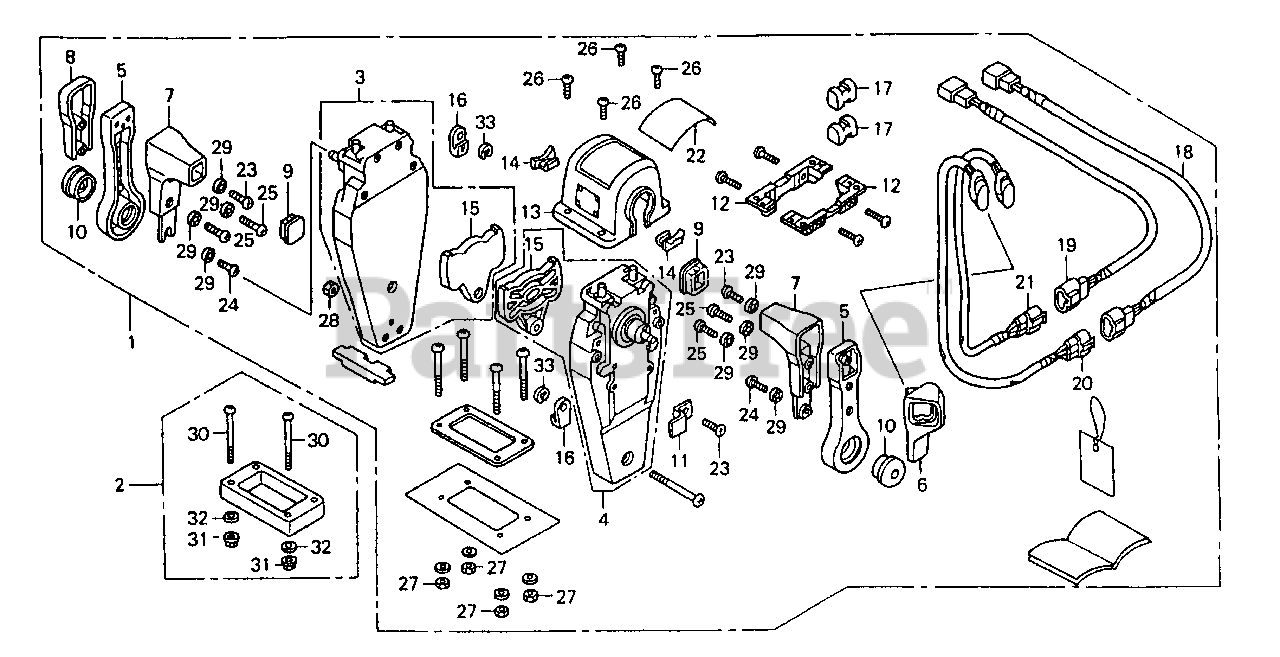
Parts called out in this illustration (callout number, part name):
1	BOX KIT, L. REMOTE CONTROL (TOP MOUNT DUAL)
2	SPACER, TOP DUAL
3	HOUSING ASSY., L. (INNER) (TOP MOUNT)
4	HOUSING ASSY., R. (INNER) (TOP MOUNT)
5	HANDLE, REMOTE CONTROL
6	COVER, L. GRIP
7	GRIP, REMOTE CONTROL HANDLE
8	COVER, DUAL GRIP
9	CAP, GRIP
10	BUTTON, THROTTLE
11	PLATE, CABLE CLAMP
12	BRACKET, REMOTE CONTROL HOUSING
13	HOUSING, DUAL REMOTE CONTROL BOX
14	HOUSING, LEAD
15	PLATE, DWELL
16	CABLE, TERMINAL
17	SPACER, CABLE CLAMP
18	SUB-HARNESS A ASSY., POWER TRIM-TILT
19	SUB-HARNESS B ASSY., POWER TRIM-TILT
20	SWITCH ASSY., POWER TRIM-TILT
21	SWITCH ASSY., POWER TRIM-TILT
22	MARK, REMOTE CONTROL (DUAL)
23	SCREW, PAN (5X16)
24	SCREW, PAN (5X10)
25	SCREW, PAN (5X20)
26	SCREW, PAN (4X10)
27	NUT, HEX. (5MM)
28	NUT, HEX. (5MM)
29	WASHER, LOCK (5MM)
30	SCREW, PAN (5X65)
31	NUT, FLANGE (5MM)
32	WASHER, PLAIN (5MM)
33	E-RING (6MM)
